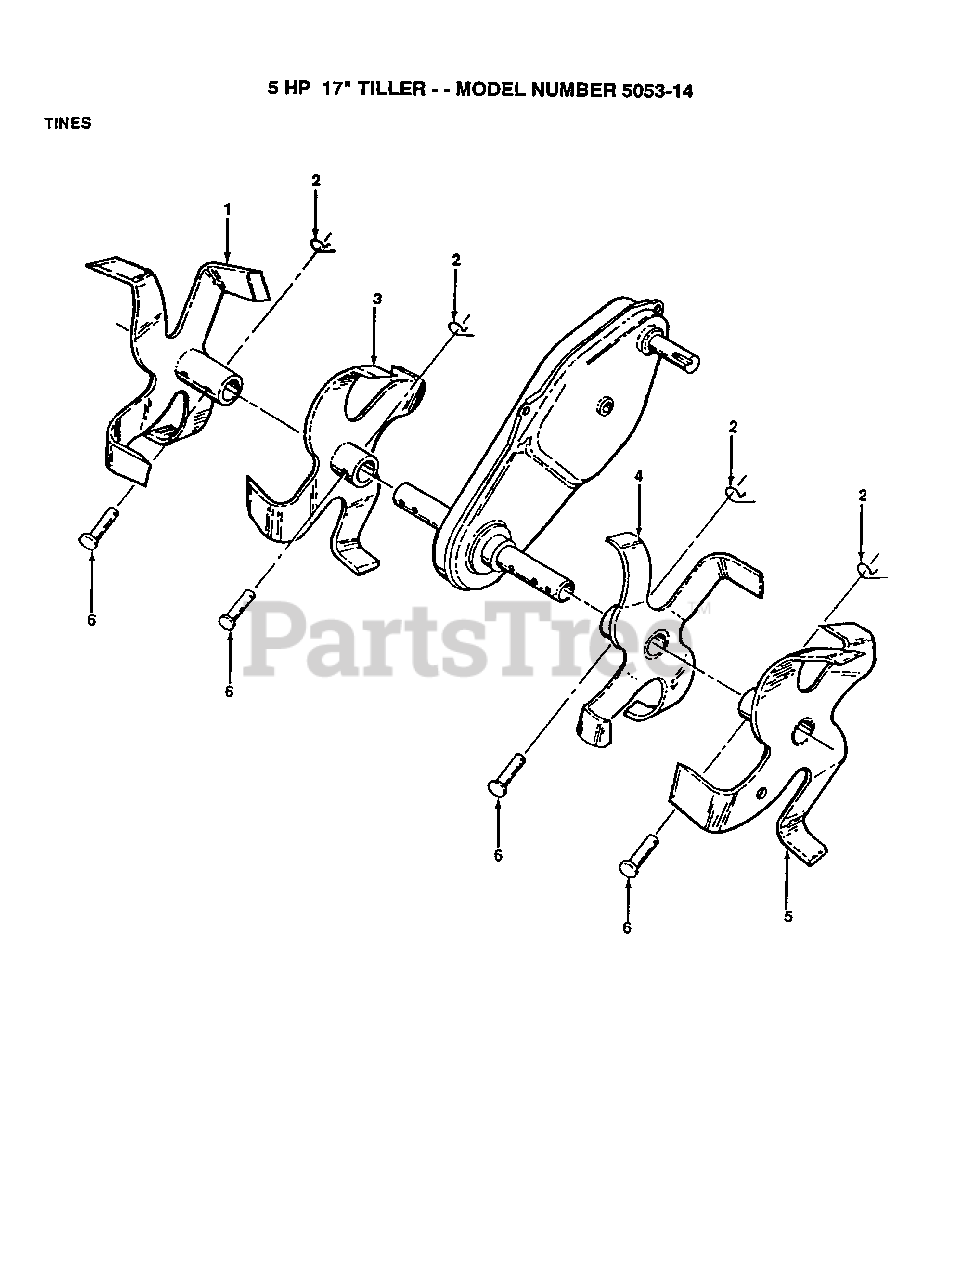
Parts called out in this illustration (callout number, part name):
1	TINE WELDMENT TI
2	RETAINER.SPRING
3	TINE TI
4	TINE TI
5	TINE WELDMENT TI
6	RIVET.PAN HD.1.75
